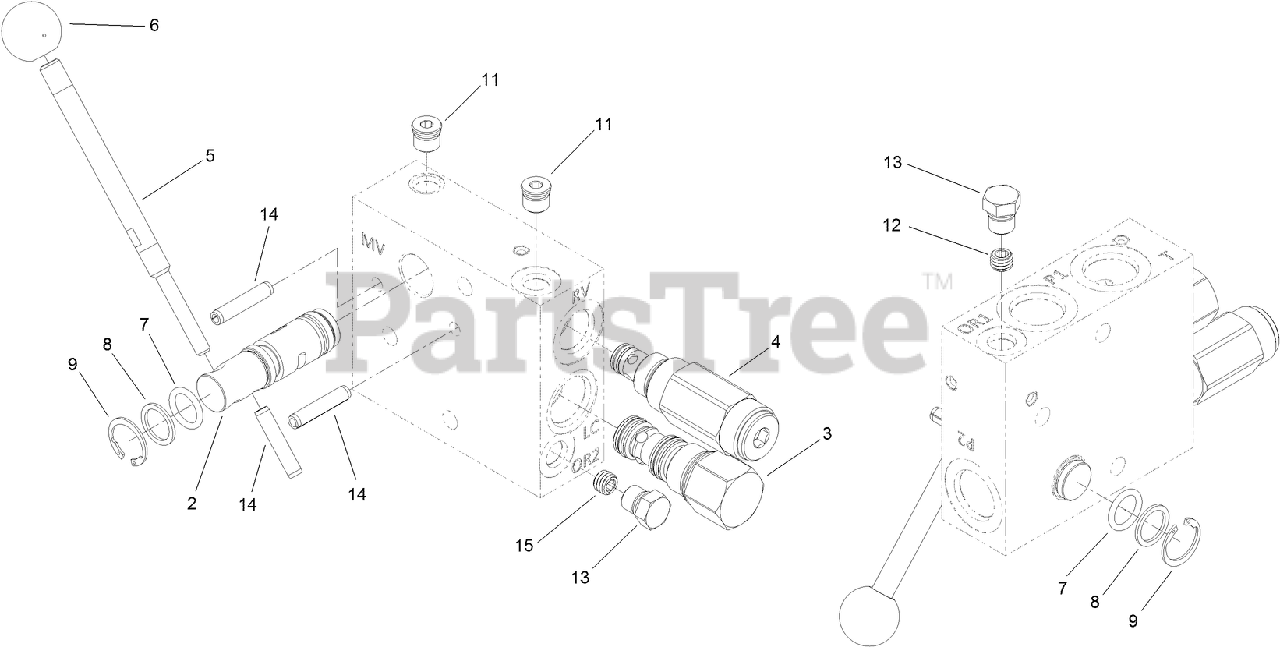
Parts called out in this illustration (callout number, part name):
2	SPOOL-ROTARY
3	SPOOL-LOGIC
4	VALVE-RELIEF
5	HANDLE-SPOOL
6	KNOB-BALL, PLASTIC
7	O-RING
8	RING-BACK UP
9	RING-RETAINING
12	PLUG-ORIFICE (0.040)
14	PIN-SPRING
15	PLUG-ORIFICE(0.015)
